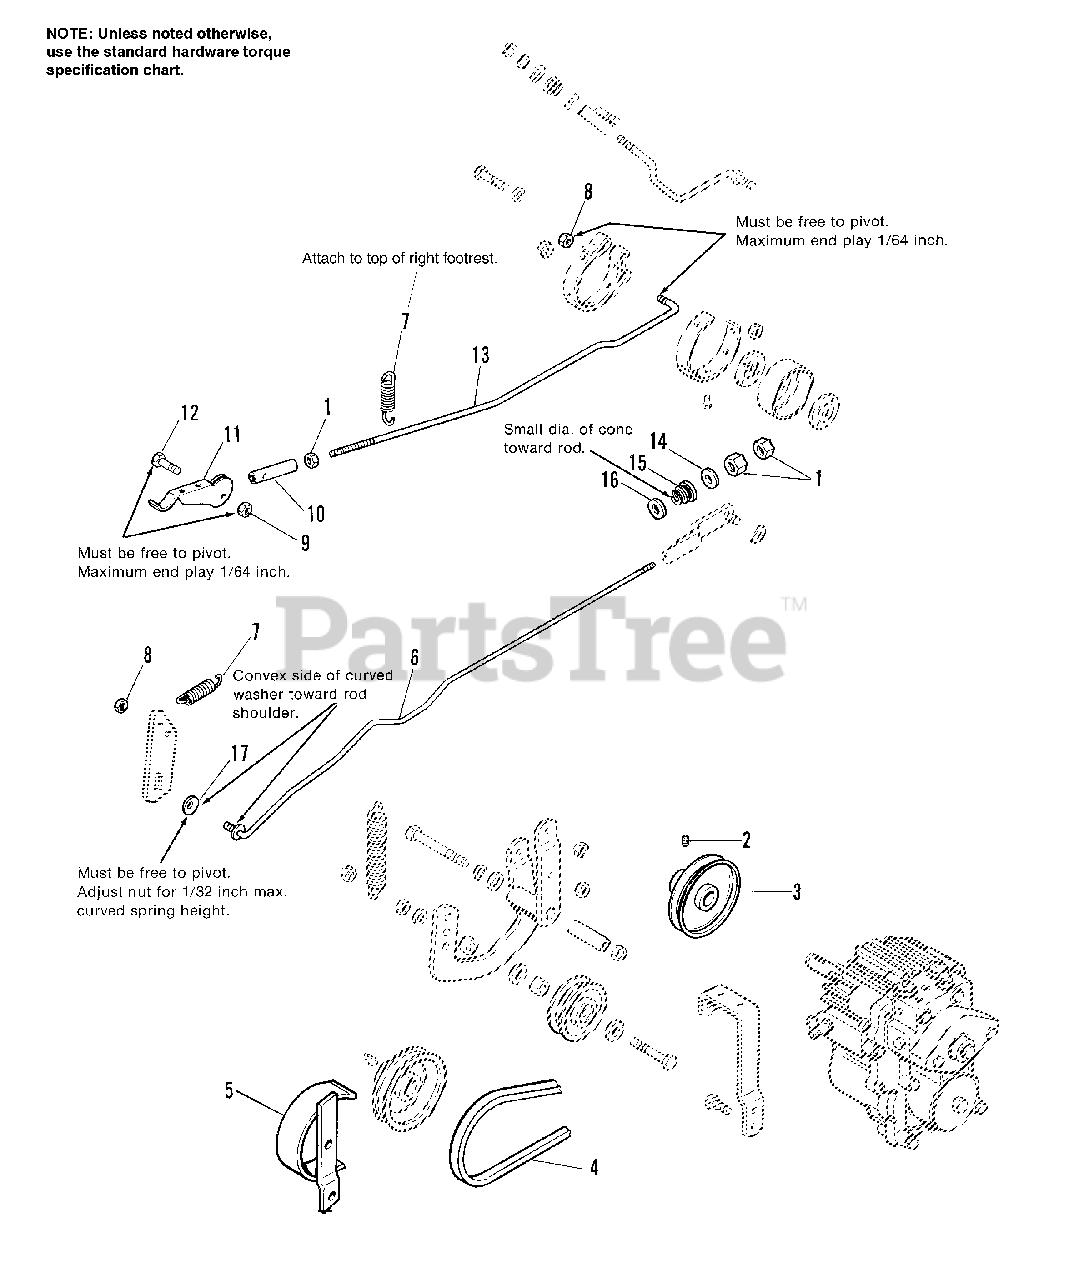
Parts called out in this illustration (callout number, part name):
1	NUT, Hex, Full, 5/16-18
2	SETSCREW, 5/16-18 x 1/2
3	PULLEY, Drive, Transmission
4	V-BELT, Drive, Transmission
5	GUARD ASSEMBLY
6	ROD, Clutch
8	LOCKNUT, Hex, 5/16-18
9	LOCKNUT, Hex, 1/4-20
11	LEVER, Parking Brake
12	CAPSCREW, Hex Hd, 1/4-20 x 1
13	ROD ASSEMBLY
14	WASHER, 5/16
15	SPRING, Cone
16	WASHER, 5/16
17	WASHER, Curved, Spring
